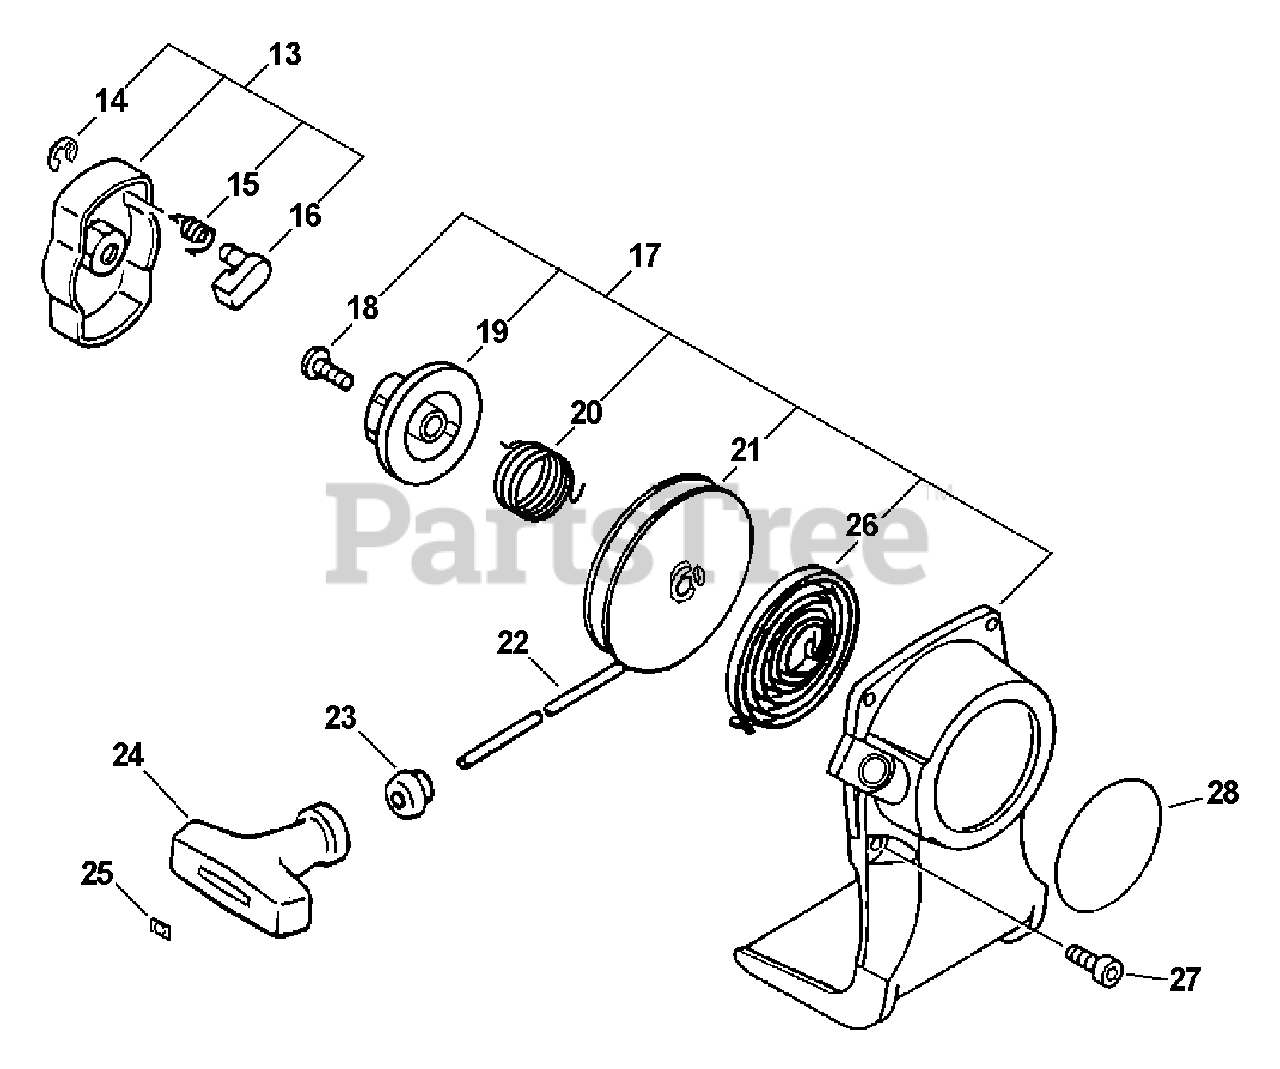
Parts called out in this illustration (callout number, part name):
13	STARTER PAWL ASSY
14	RING, RETAINING - 4
15	SPRING, RETURN
16	PAWL, STARTER
17	STARTER ASSY
18	SCREW
19	PLATE, CAM
20	SPRING, DAMPER
21	REEL, ROPE
22	ROPE, STARTER - 3X700
23	GUIDE, ROPE
24	GRIP, STARTER
25	RETAINER, ROPE
26	SPRING, REWIND
27	SCREW - 4X16
28	LABEL - ECHO -- i-30
